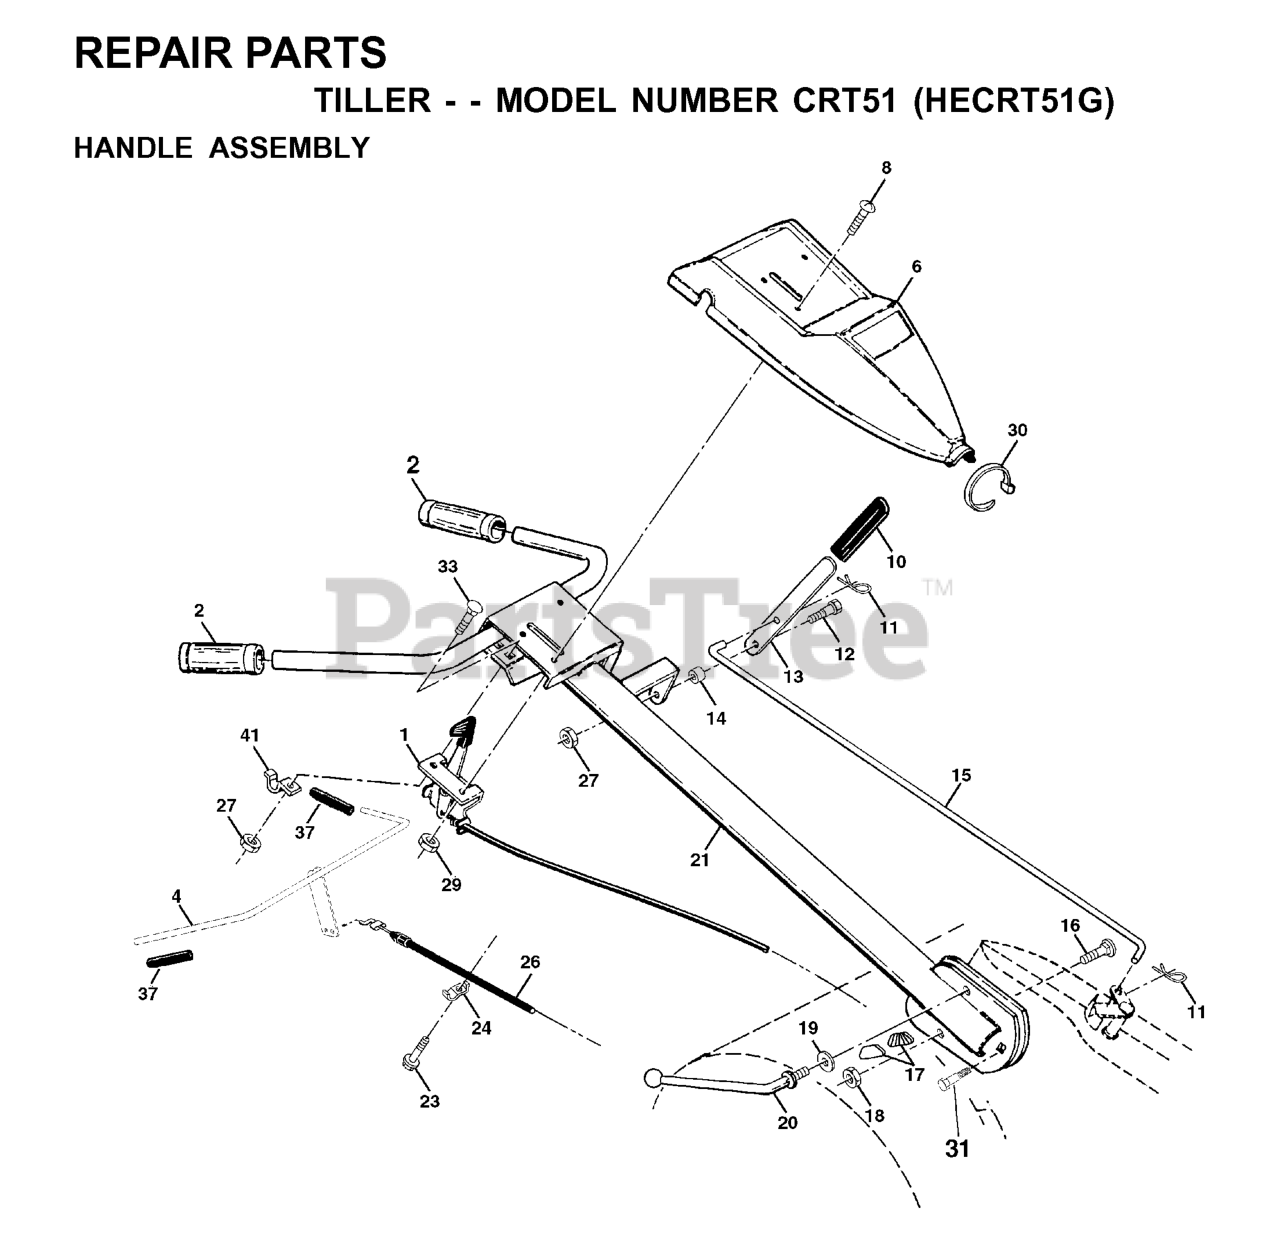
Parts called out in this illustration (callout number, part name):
1	CONT,THROTTLE
2	KIT.GRIP.HANDLE.5.00.BLK.VINYL
4	CONTROL BAR ASSY
8	SCREW.PNHD.10-24
10	GRIP T
11	RETAINER M
12	SHOULDER BOLT ST
13	SHIFT HANDLE CRT
14	GROMMET.RUBBER.CRT.TILLER
15	SHIFT ROD CRT
16	BOLT D
17	LOCK.HANDLE.CRT
19	WASHER CRT
20	LEVER.LOCK.CRT
21	HANDLE ASSY
23	SCREW.HEX.WSH.SLT.#10-24X.50
24	CONDUIT.CLIP.PLATED
26	CABLE.CLUTCH
27	NUT T
29	NUT **
30	TIE CABLE CRT
31	BOLT.PIVOT
37	GRIP BAR CRT(1)
41	CLAMP.BAR.CRT.BLACK
